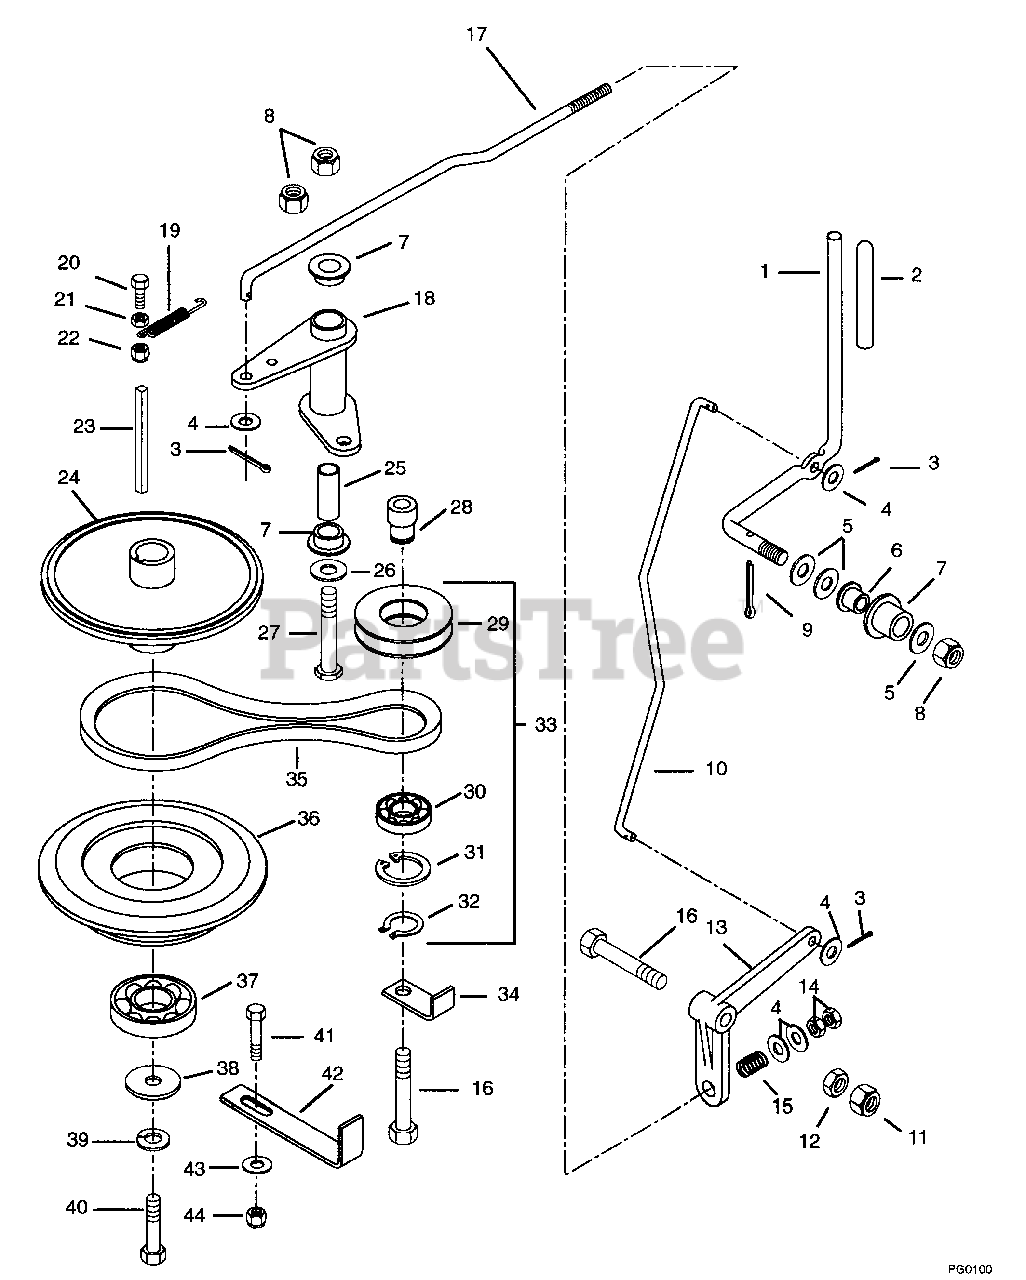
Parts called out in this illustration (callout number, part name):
1	Lever, PTO Actuating
2	Grip, PTO Lever
3	Pin-Cotter .09 x .75
4	Washer-Flat-Steel .406 x .812 x .065
5	Washer-Flat-Steel .531 x 1.250 x .100
6	Bushing-Flange .515 x .750 x .745 x 1.00
7	Bushing-Flange .762 x 1.0 x .580 x 1.48
8	Nut-Locking-Nylon .50-13 Grade 5
9	Pin-Cotter .188 x 1.25
10	Rod, PTO Control
11	Nut-Locking .50-13
12	Nut-Jam .50-13 Grade 2
13	Lever, PTO Clutch
14	Nut-Hex .375-16 Grade 2
15	Spring-Compression .125 x .78 x 1.00
16	Bolt-Hex .50-13 x 2.50 Grade 5
17	Rod, PTO Clutch Actuating
18	Weldment, PTO Idler Arm
19	Spring-Tension .06 x .50 x 3.5
20	Bolt-Hex .31-18 x 1.00 Grade 5
21	Nut-Hex .312-18 Grade 2
22	Nut-Locking-Nylon .312-18 Grade 2
23	Key-Square .250 x 3.60 x .250
24	Hub, PTO Clutch
25	Bushing, .560 x .745 x 4.20
26	Washer-Flat-Steel .531 x 1.062 x .095
27	Bolt-Hex .50-13 x 5.00
28	Bushing, Flange .515 x .787 x 1.41
29	Sheave, Idler
30	Bearing-Ball 1.85 x .787 x .55
31	Ring-Retaining-Internal 2.054 x .062
32	Ring-Retaining Truarc
33	Assembly, Idler Sheave
34	Guard, Belt
35	V-Belt A-Section
36	Sheave, Mower Clutch
37	Bearing-Ball 1.57 x 3.15 x .71
38	Washer-Special .469 x 2.000 x .250
39	Washer-Lock .44 Reg
40	Bolt-Hex .44-20 x 2.25 Grade 5
41	Bolt-Hex .38-16 x 1.00 Grade 5
42	Guide, V-Belt PM-250
43	Washer-Flat-Steel .406 x .812 x .065
44	Nut-Locking-Nylon .375-16 Grade 2
